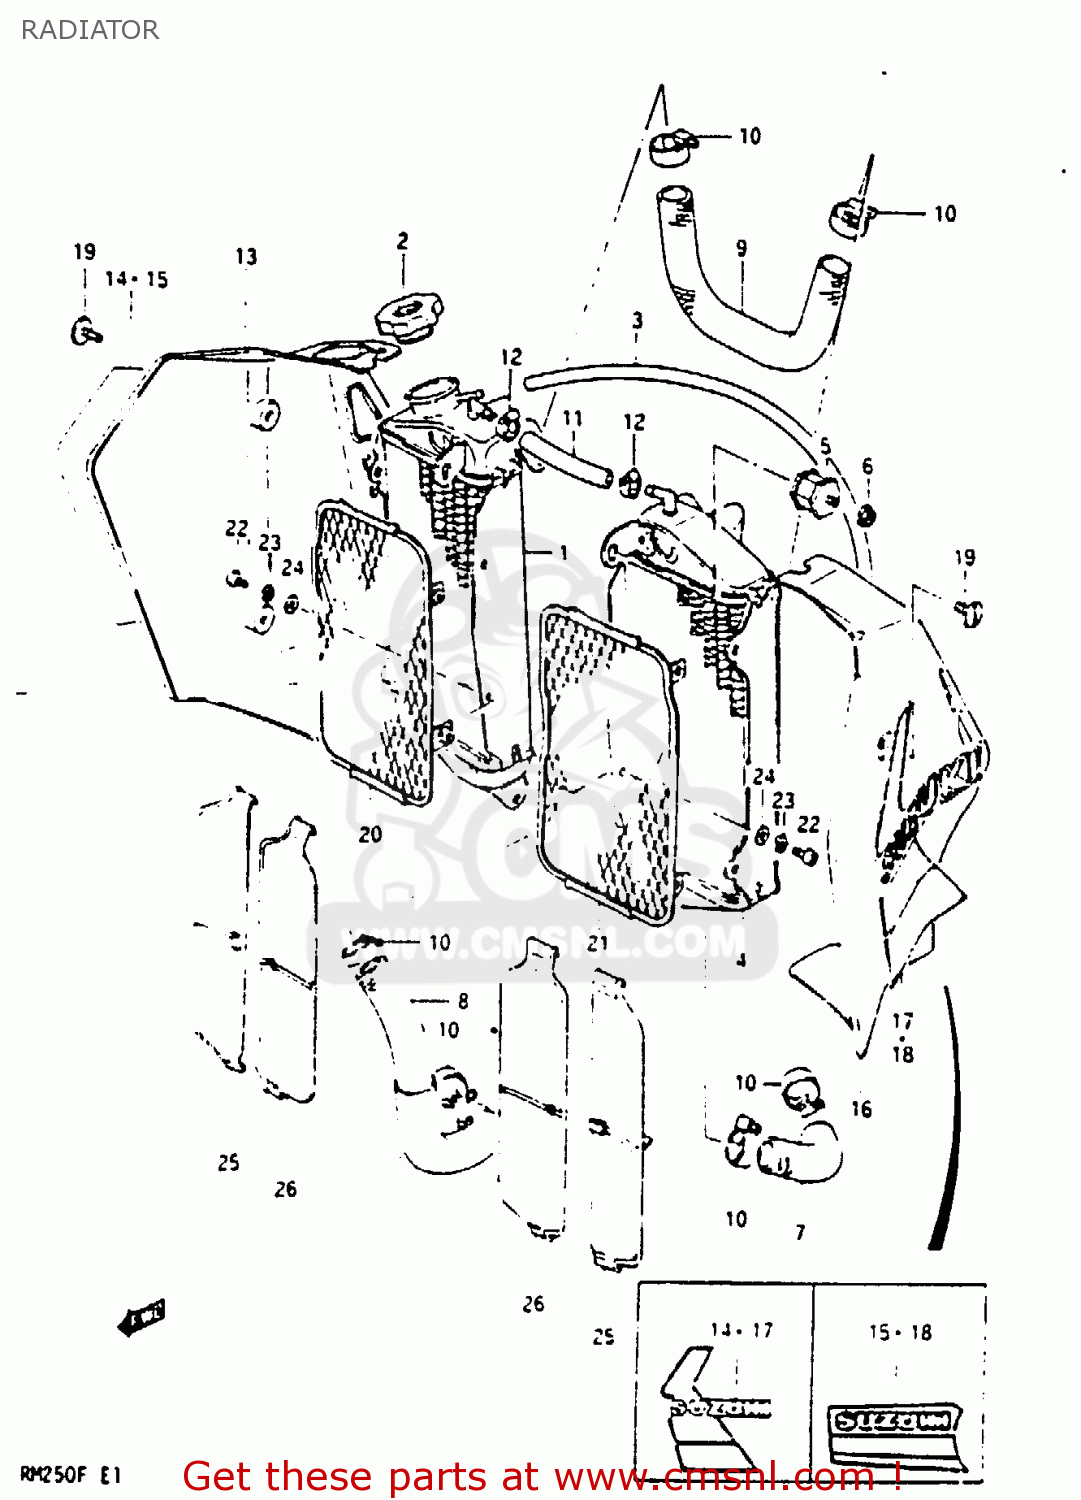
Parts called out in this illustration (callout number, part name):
1	RADIATOR ASSEMBLY,WATER
2	CAP,RADIATOR 1.1
3	HOSE
4	RADIATOR ASSEMBLY,WATER
5	CUSHION,RADIATOR
6	NUT 6MM
7	HOSE,RADIATOR
8	HOSE,RADIATOR OUTLET
9	HOSE,RADIATOR JOINT
10	CLAMP
11	HOSE,WATER
12	CLAMP
13	COVER,RADIATOR,RIGHT
14	TAPE SET
15	TAPE SET,RADIATOR COVER
16	COVER,RADIATOR,LEFT
17	TAPE SET
18	TAPE SET,RADIATOR COVER
19	SCREW(6X14)
20	BUMPER,RADIATOR,RIGHT
21	BUMPER,RADIATOR,LEFT
22	SCREW
23	LOCK WASHER
24	WASHER
25	LOUVER,RADIATOR MUD GUARD
26	LOUVER,RADIATOR MUD GUARD
